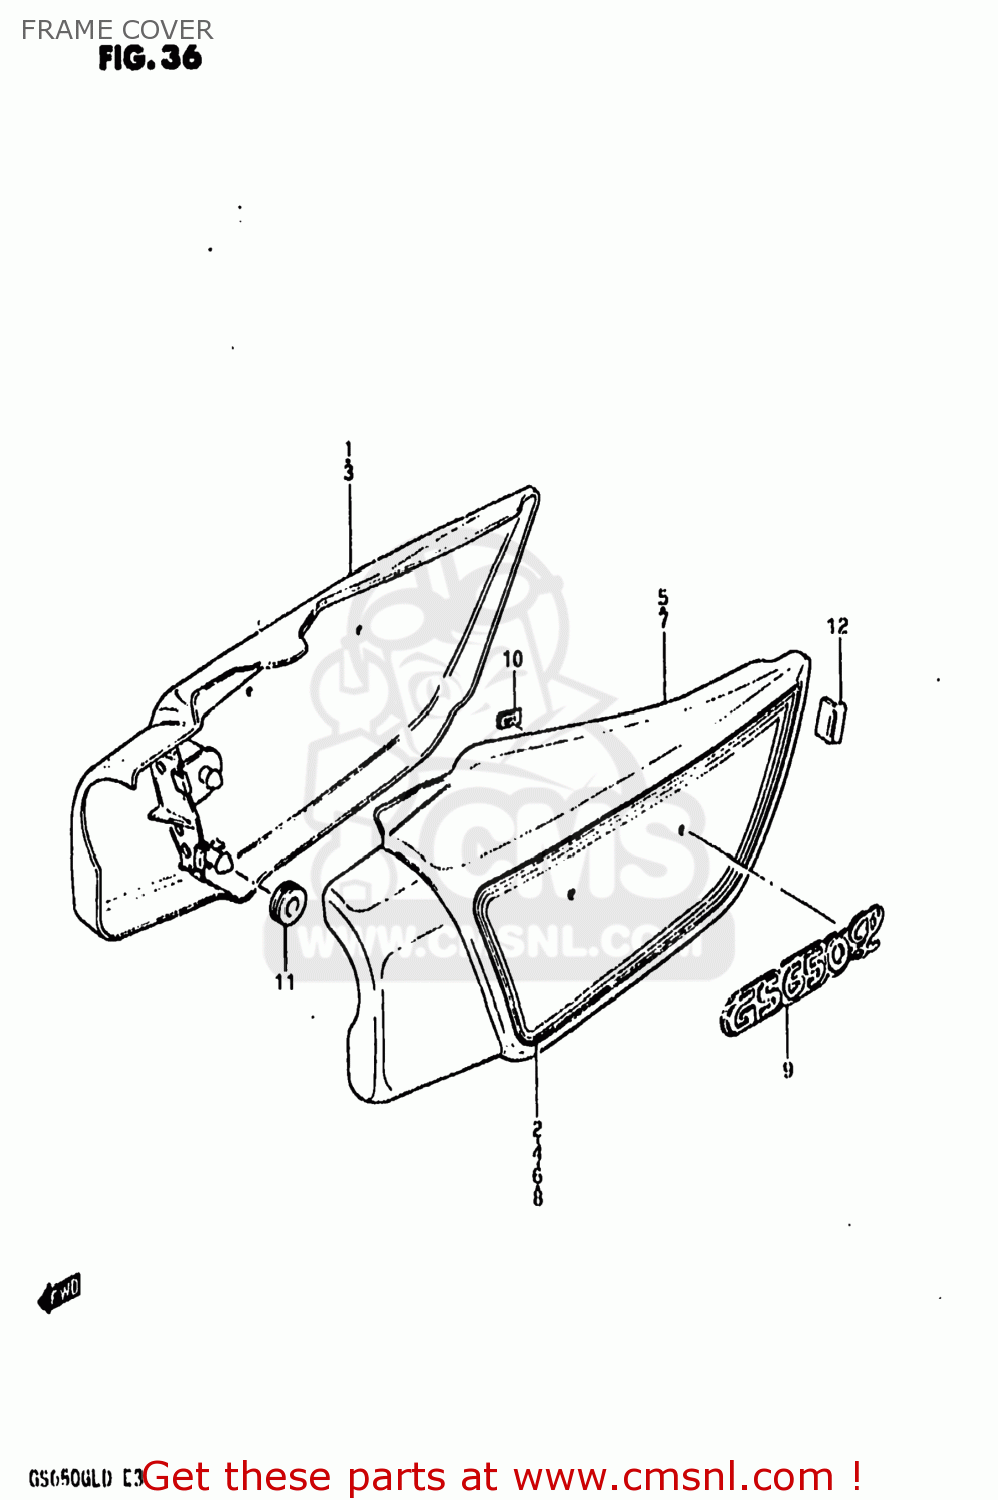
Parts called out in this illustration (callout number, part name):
1	COVER ASSEMBLY,FRAME,RIGHT
2	TAPE SET,FRAME COVER
3	COVER ASSEMBLY,FRAME,RIGHT
4	TAPE SET,FRAME COVER
5	COVER ASSEMBLY,FRAME,LEFT
6	TAPE SET,FRAME COVER,LEFT
7	COVER ASSEMBLY,FRAME,LEFT
8	TAPE SET,FRAME COVER,LEFT
9	EMBLEM,FRAME COVER
10	NUT
11	CUSHION
12	CUSHION,FRAME COVER
